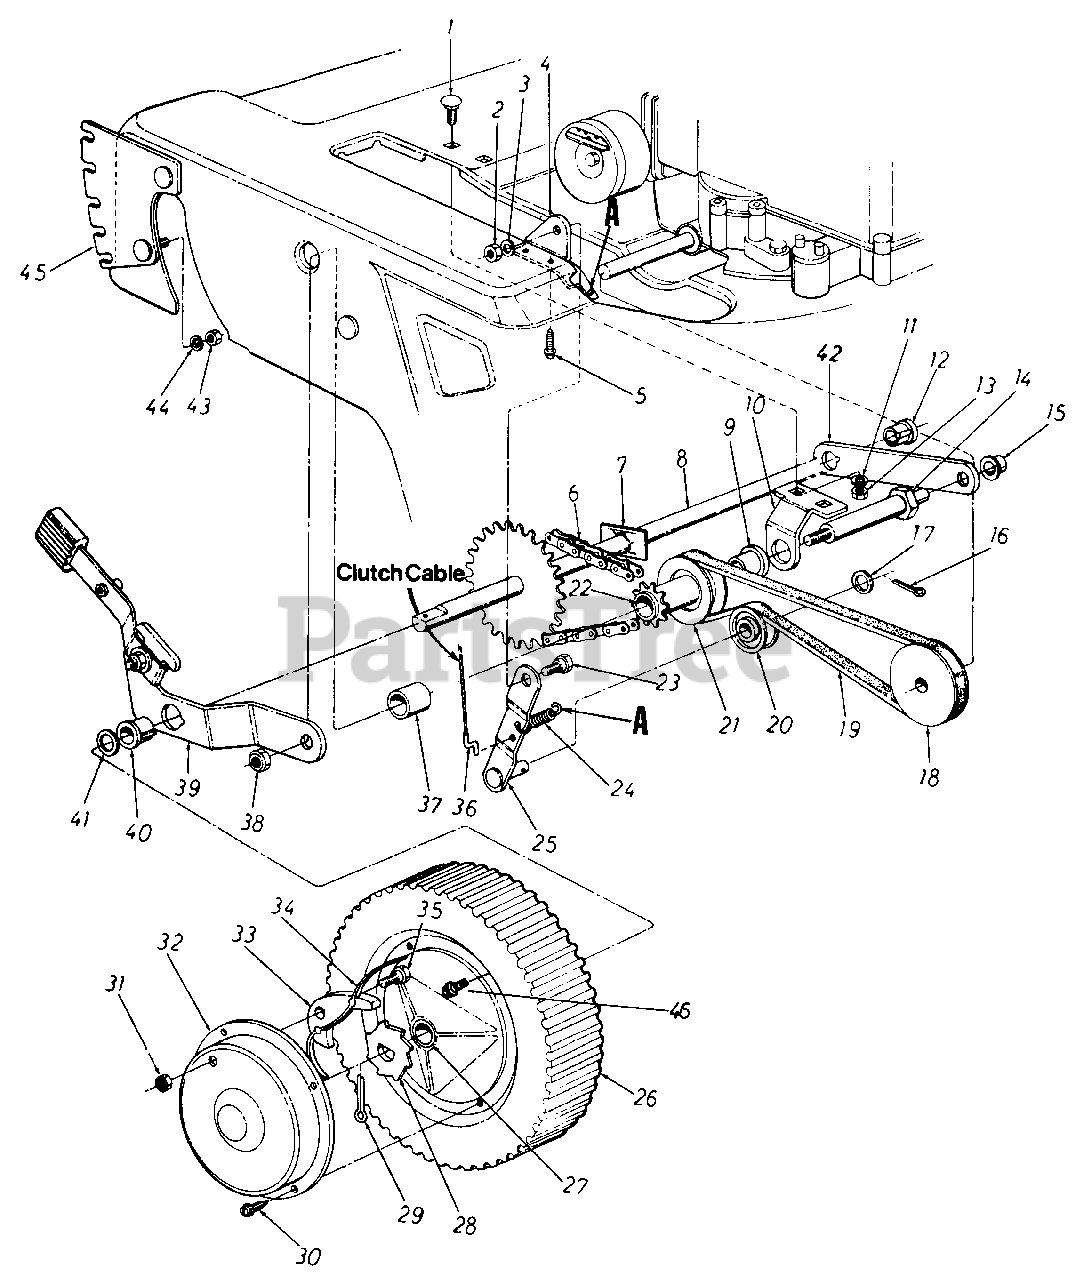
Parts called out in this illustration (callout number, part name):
1	Carriage Bolt 5/16-18 x .62" Lg.
2	Hex Nut 5/16-18 Thd.
3	L-Wash. 5/16" I.D.
4	Cam Bracket
5	Hex Wash. Hd. "AB" Tap Scr. 1/4-20 x .62" Lg.
6	#48 Chain 1/2" Pitch x 31 Links
7	Push Clip .692 Dia.
8	Rear Shaft Ass'y.
9	Flange Bearing .631" I.D.
10	Bracket
11	L-Wash. 5/16" I.D.
12	Flange Bearing
13	Hex Nut 5/16-18 Thd.
14	Shld. Bolt .625" Dia. x 3.380 (Special)
15	Cap Speed Nut .50" Dia.
16	Cotter Pin 1/8" Dia. x 1.00" Lg.
17	Fl-Wash. .531 I.D. x .930 O.D. x .050
18	Engine Pulley
19	"V"-Belt 1/2" x 24" Lg.
20	Plastic Flat Idler
21	Pulley with 9 Tooth Sprocket Ass'y.
22	Sleeve Bearing .62" I.D. x .75" O.D. x .94 Lg.
23	Shld. Bolt .375" Dia. x .171 Lg.
24	Ext. Spring .33" O.D. x 1.12" Lg.
25	Idler Bracket Ass'y.
26	Rear Wheel Ass'y. Comp. 8.0 x 1.75
27	Flange Bearing - Plastic .50" I.D. x 1.13" O.D.
28	Ratchet - Rear Wheel
29	Cotter Pin 1/8" Dia. x 1.00" Lg.
30	Pan Hd. "AB" Tap Scr. #12 x .50" Lg.
31	Hex Ins. L-Nut 1/4-20 Thd.
32	Hub Cap
33	Pawl - Rear Wheel
34	Spring - Nylon
35	Shld. Bolt .342" Dia. x .268" Lg.
36	Clutch Control Cable 48.0" Lg. x 3.12" Ext.
37	Spacer .635 I.D. x .88 O.D. x .910
38	Hex Nut 5/16-18 Thd.
39	Pivot Bracket Ass'y. - R.H.
40	Flange Bearing
41	Fl-Wash. .531 I.D. x .93 O.D. x .050
42	Support Link
43	Hex Nut 5/16-18 Thd.
44	L-Wash. 5/16" I.D.
45	Index Plate Ass'y. - R.H.
46	Hex Wash. Hd. Self-Tap Scr. #8 x .50" Lg.
